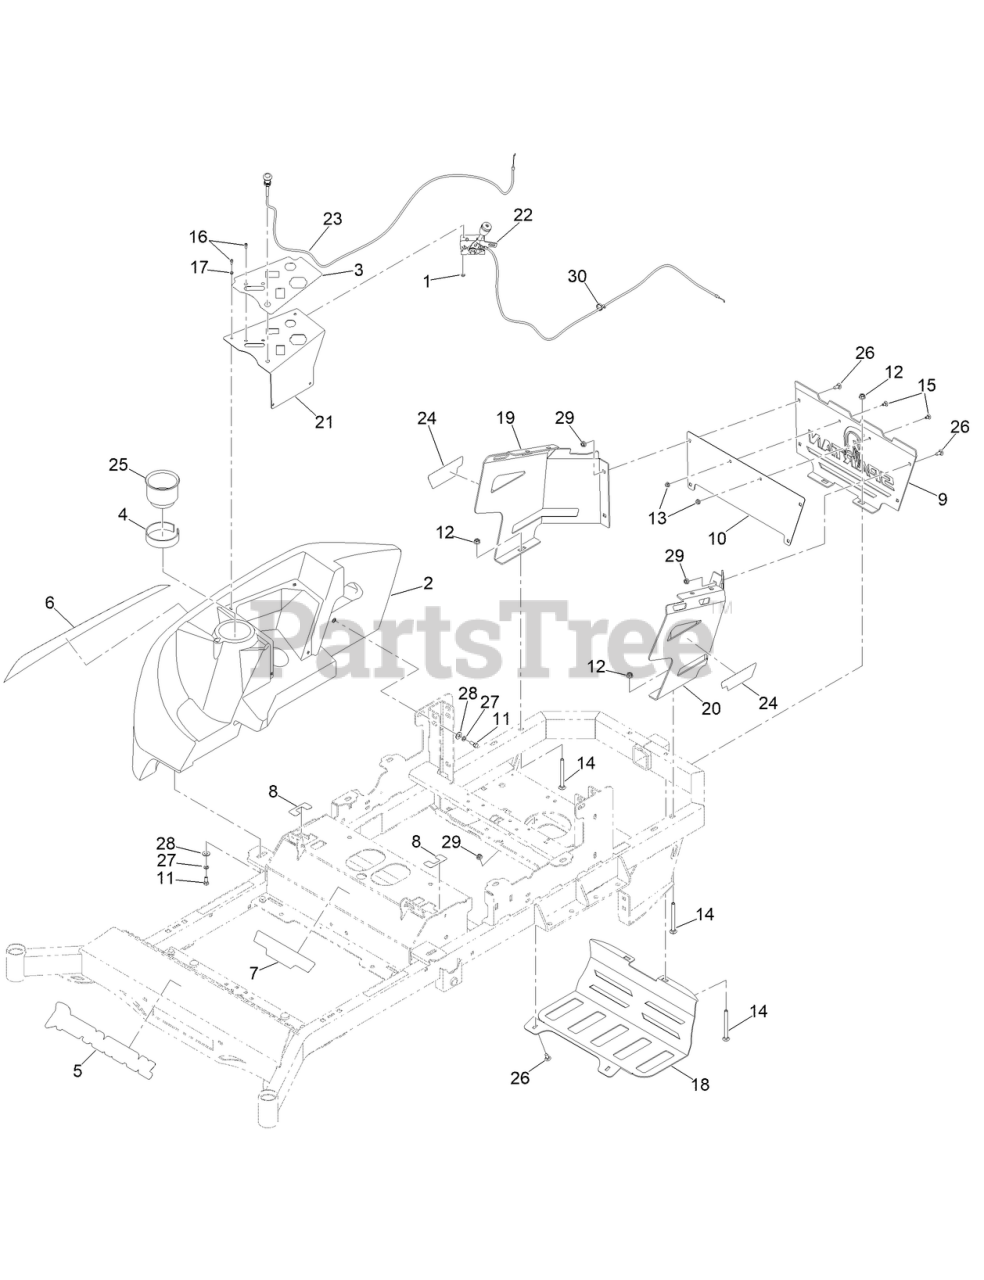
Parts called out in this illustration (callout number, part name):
1	NUT-LOCK
2	CONSOLE W/ CUPHOLDER
3	DECAL-CONTROL PANEL
4	TAPE-FOAM
5	DECAL-SPARTAN, FRONT
6	DECAL-TANK
7	DECAL-RZ-HD GT TRAC MODEL
8	DECAL-MOTION CONTROL
9	PLATE - ENGINE COWLING
10	PLATE -BACKER PLATE
11	SCREW-HH
12	3/8-16 NYLON INSERT FLANGE L/NUT YZ
13	1/4-20 HEX FLANGE NUT W/SERR ZINC
14	3/8-16 X 4 CARRIAGE BOLT ZINC
15	1/4-20 X 1/2 CARRIAGE BOLT,YZ
16	10-24 X 1/2 SOCKET C/S 18-8 SS
17	#10 SPLIT LOCKWASHER 18-8 SS
18	MUFFLER GUARD [GRAY]
19	2021 RT/SRT ENGN COWLING RTPAINTED
20	2021 RT/SRT ENGN COWLING LT PAINTED
21	RT 45 KEY MNT
22	MWR THROTTLE CABLE ASSY W / HANDLE
23	MWR CHOKE CABLE ASSM
24	DECAL-MODEL
25	CUP HOLDER
26	BOLT-CARR
27	WASHER-LOCK
28	WASHER-FLAT
30	TIE-CABLE
